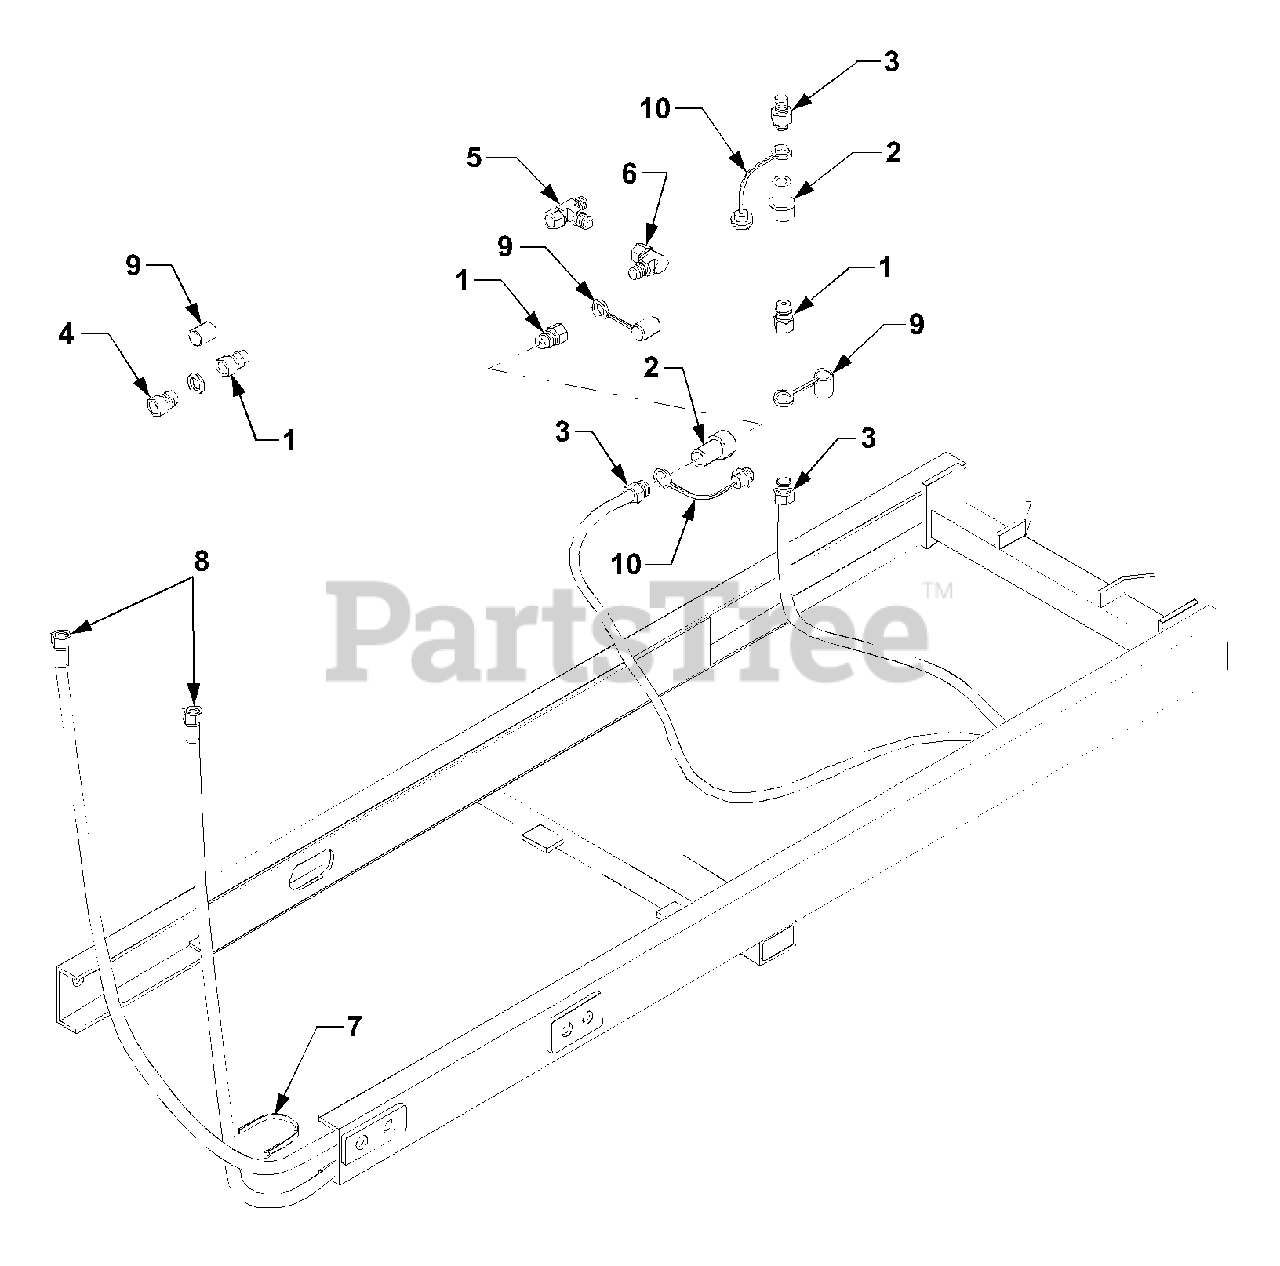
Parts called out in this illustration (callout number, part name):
1	Quick Coupler - Male
2	Quick Coupler - Female
3	Nipple w/O-ring
6	Adapter Elbow
9	Quick Coupler Cover
10	Quick Coupler Cover
